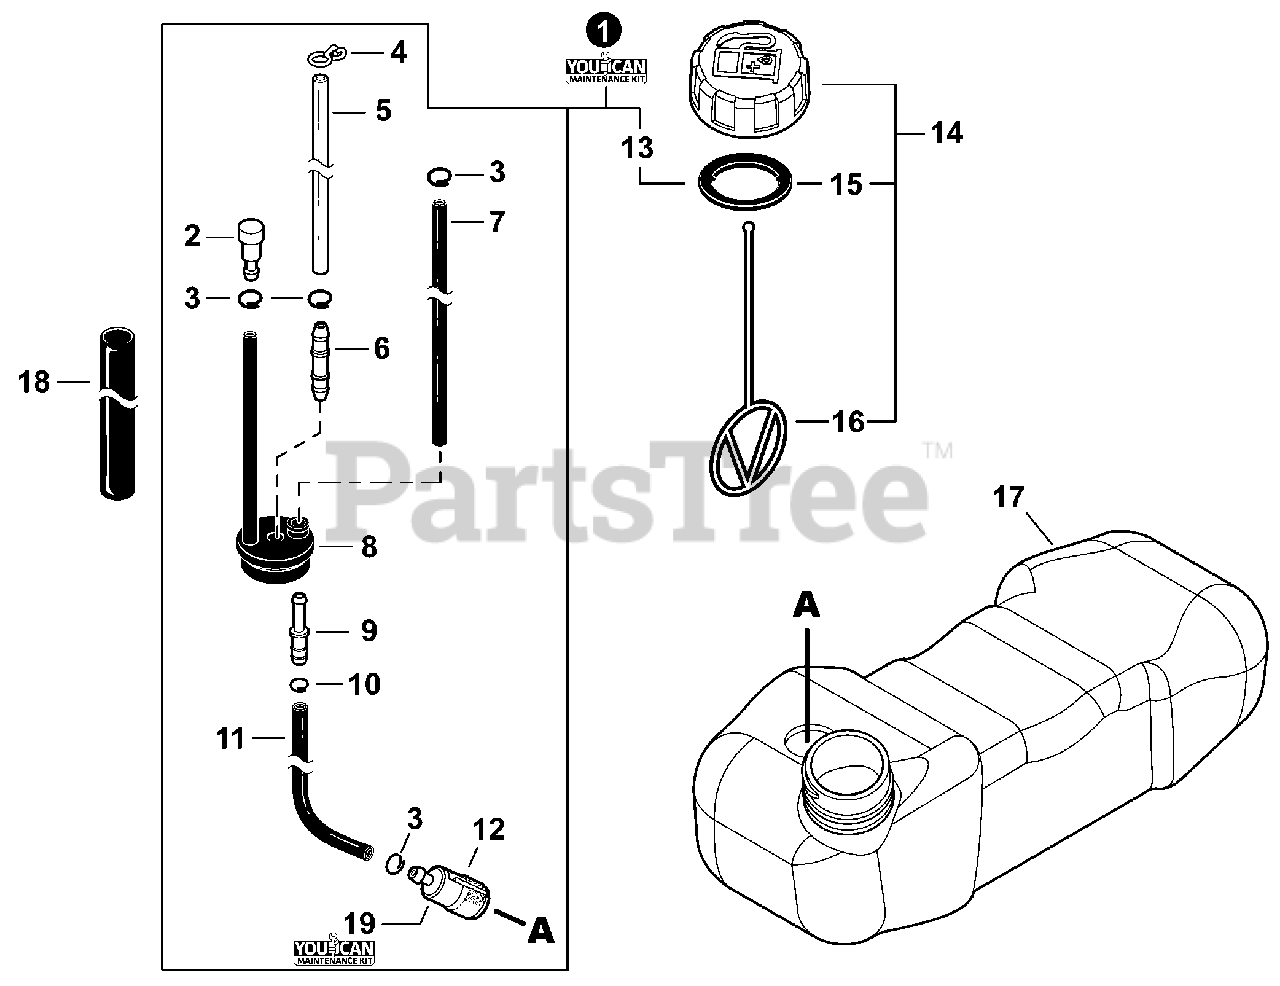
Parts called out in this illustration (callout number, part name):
1	FUEL SYSTEM KIT - YOUCAN™
2	VENT ASSY
3	CLIP Ø6
4	CLIP, SPRING Ø5.2
5	PIPE, FUEL 3×6×133 CLEAR
6	CONNECTOR, PIPE
7	PIPE, FUEL 3×5×145 BLACK
8	GROMMET, FUEL W/VENT PIPE
9	CONNECTOR, PIPE Ø5ר3.5
10	CLIP Ø6.5MM
11	PIPE, FUEL 3.3×6×195 BLACK
12	FILTER, FUEL
13	GASKET, FUEL CAP
14	CAP ASSY, FUEL
15	GASKET, FUEL CAP
16	CONNECTOR, CAP L= 100mm
17	TANK, FUEL
18	TUBE, PROTECTIVE
19	TUNE-UP KIT - YOUCAN™
